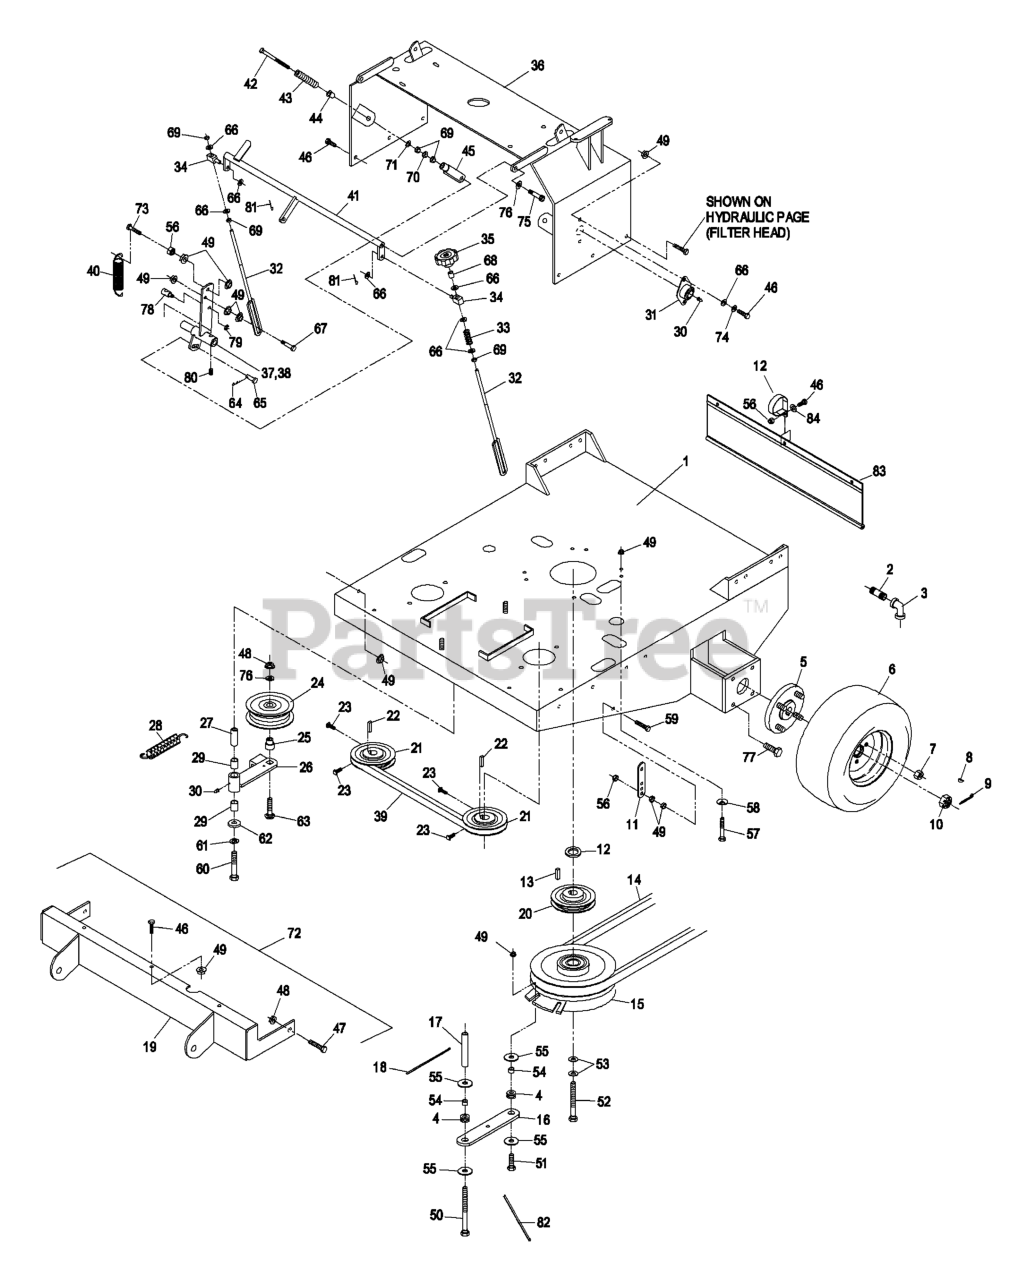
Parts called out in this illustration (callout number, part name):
2	NIPPLE,PIPE
3	ELBOW-90 DEG
4	GROMMET
6	WHEEL AND TIRE ASM
7	NUT-LUG
8	KEY-WOODRUFF
9	PIN-COTTER
10	NUT-HEX, SLOTTED
11	TAB-SPRING, EXTENSION
14	BELT,DECK DRIVE
15	KIT, CLUTCH ASSY
16	STRAP-CLUTCH, BRAKE
18	TIE-CABLE
19	WLD,SULKY HITCH
20	PULLEY
21	SHEAVE ASM
23	SCREW-SET
25	BUSHING-IDLER
26	IDLER ARM ASM
27	BUSHING
28	SPRING-EXTENSION
29	SLEEVE-BEARING
30	FITTING-GREASE
31	BEARING-FLANGE, SIDE
32	LINK,SPEED CONTROL
33	SPRING-COMPRESSION
35	KNOB-TRACKING
40	SPRING-EXTENSION
42	BOLT-RETURN, NEUTRAL
43	SPRING-RETURN, NEUTRAL
44	BUSHING-FLANGED
45	YOKE-ADJUSTABLE
46	SCREW-HH
47	SCREW-HH
48	NUT-HHF, WHIZ
49	Nut, 5/16-18 Whizlock
50	SCREW-HH
51	SCREW-HH
52	SCREW-HH
53	WASHER-SPRING
56	NUT-LOCK, NI
57	SCREW-HH
58	WASHER-SPRING
59	BOLT-TAP, HH
60	BOLT-CARR
61	WASHER-LOCK
63	SCREW-CARR
64	PIN-COTTER
65	PIN-CLEVIS
66	WASHER-PLAIN
67	SCREW-HH
69	NUT-HEX
70	NUT-JAM
71	WASHER-FLAT
72	Hitch Kit, Sulky
73	SCREW-HH
74	WASHER-LOCK
75	SCREW-HSH
76	WASHER-FLAT
77	SCREW-HHF
79	RING-CLIP
80	SCREW-SET
81	PIN-COTTER
82	TIE-PLASTIC
83	SHIELD,DRAG
84	WASHER-FLAT
